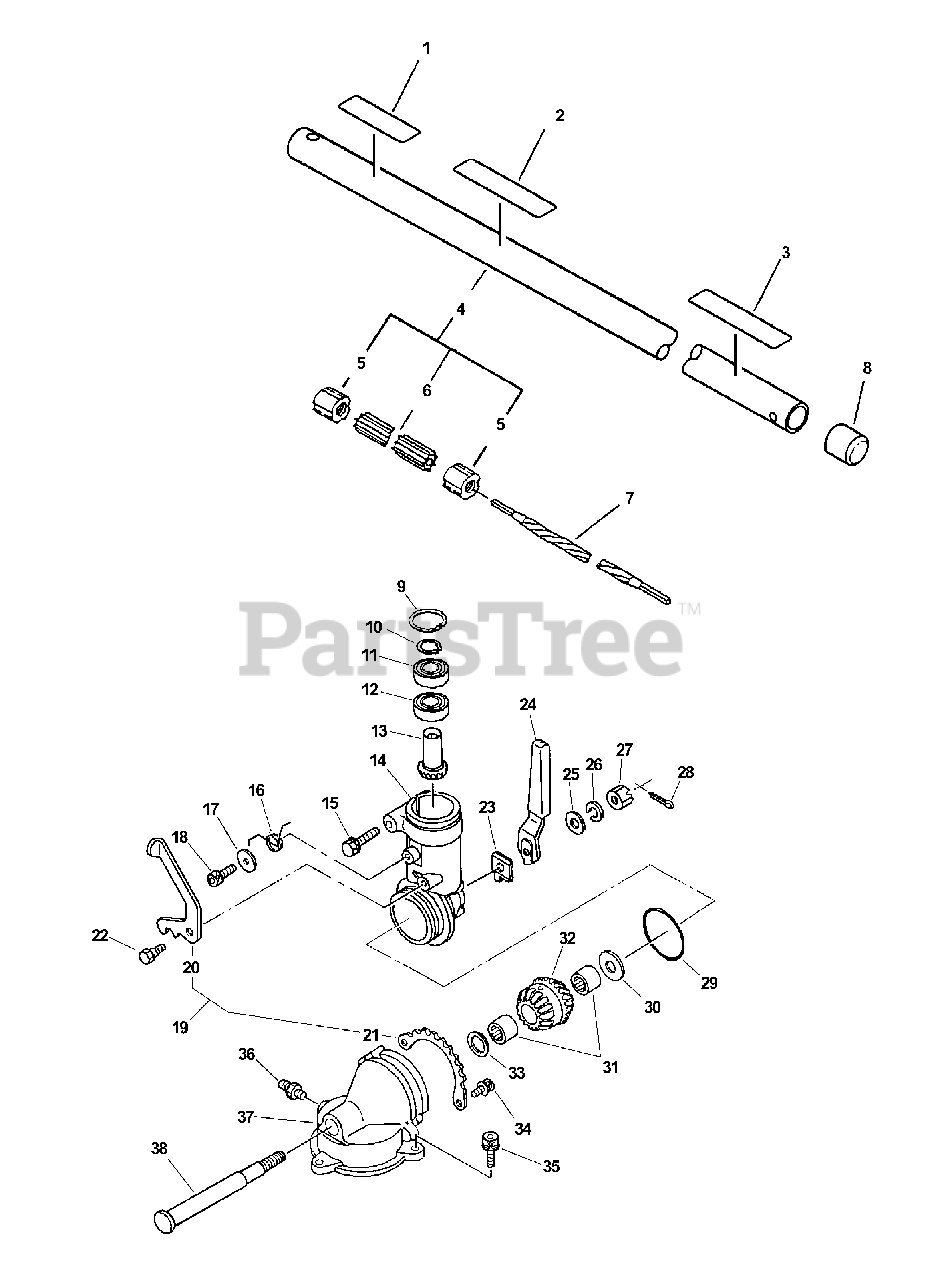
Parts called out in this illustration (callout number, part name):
1	LABEL - CAUTION
2	LABEL - CAUTION
3	LABEL - CAUTION
4	MAIN PIPE ASSY
6	LINER - FLEXIBLE
7	DRIVESHAFT - FLEXIBLE
9	RING, RETAINING - 22
10	RING, RETAINING - 10
11	BEARING, BALL - 6900Z
12	BEARING, BALL - 6900
13	GEAR - DRIVE
14	CASE, GEAR
15	BOLT - 5X35
17	WASHER - 5
18	SCREW - 5X14
19	LATCH RESETTER SET
21	RESETTER, LATCH
22	BOLT - 5
23	PLATE, ANGLE
24	PIECE, LEVER
25	WASHER, THRUST
26	LOCKWASHER - 6
27	NUT - 6 -- SLOTTED
28	PIN, SPLIT - 1.6X16
29	O-RING - 32
30	WASHER - 8
31	BEARING, NEEDLE
32	GEAR - BEVEL
33	WASHER - 10
34	SCREW - 4X10
35	SCREW - 5X18
36	FITTING, GREASE
37	LID, GEAR CASE
38	GEAR - SHAFT
